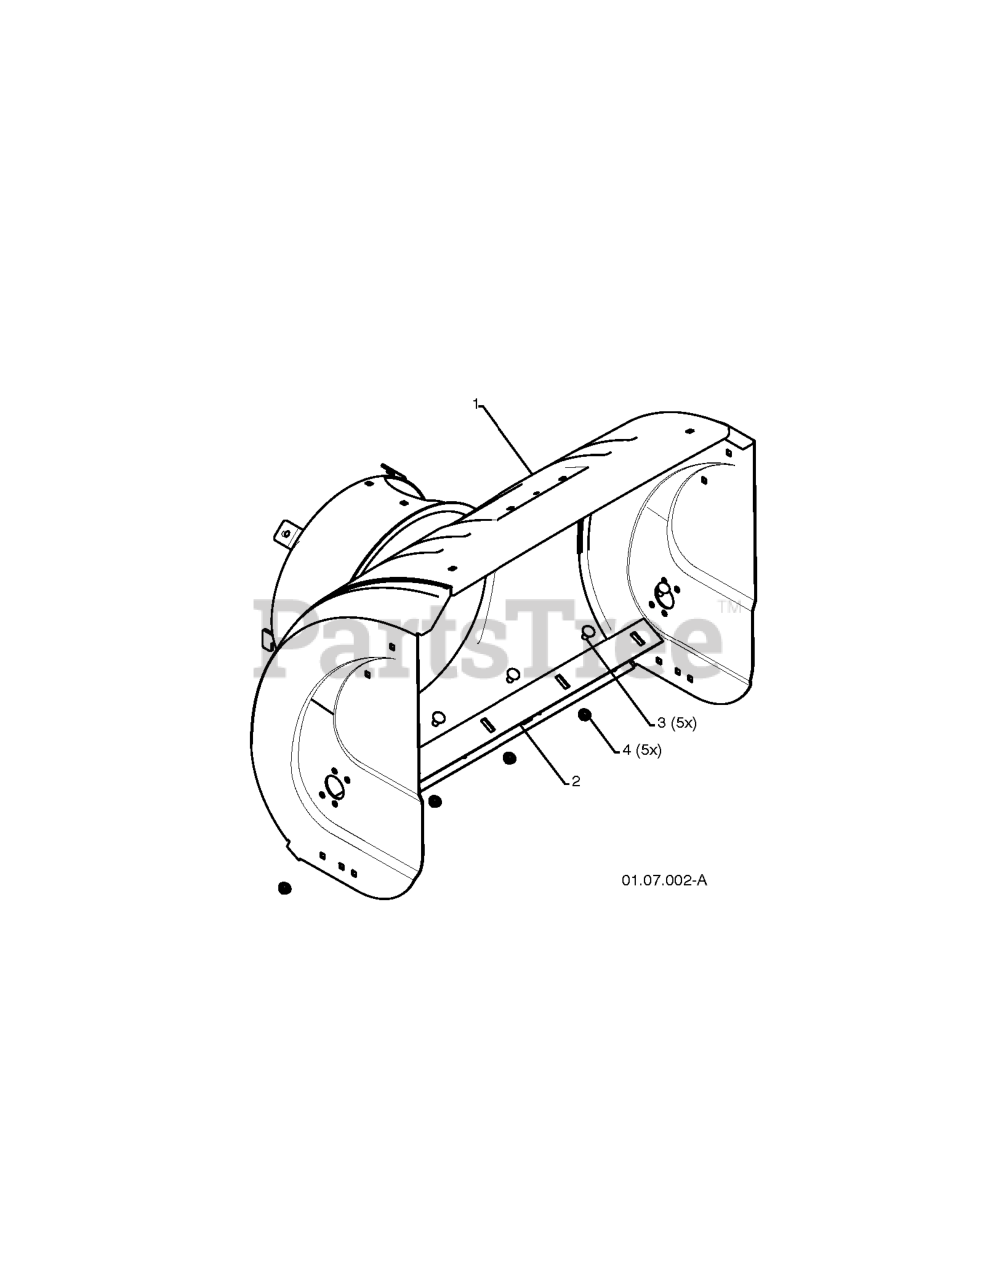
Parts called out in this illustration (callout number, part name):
1	HOUSING, AUGER
2	BAR, SCRAPER
3	BOLT
4	NUT.FLANGE.5/16
